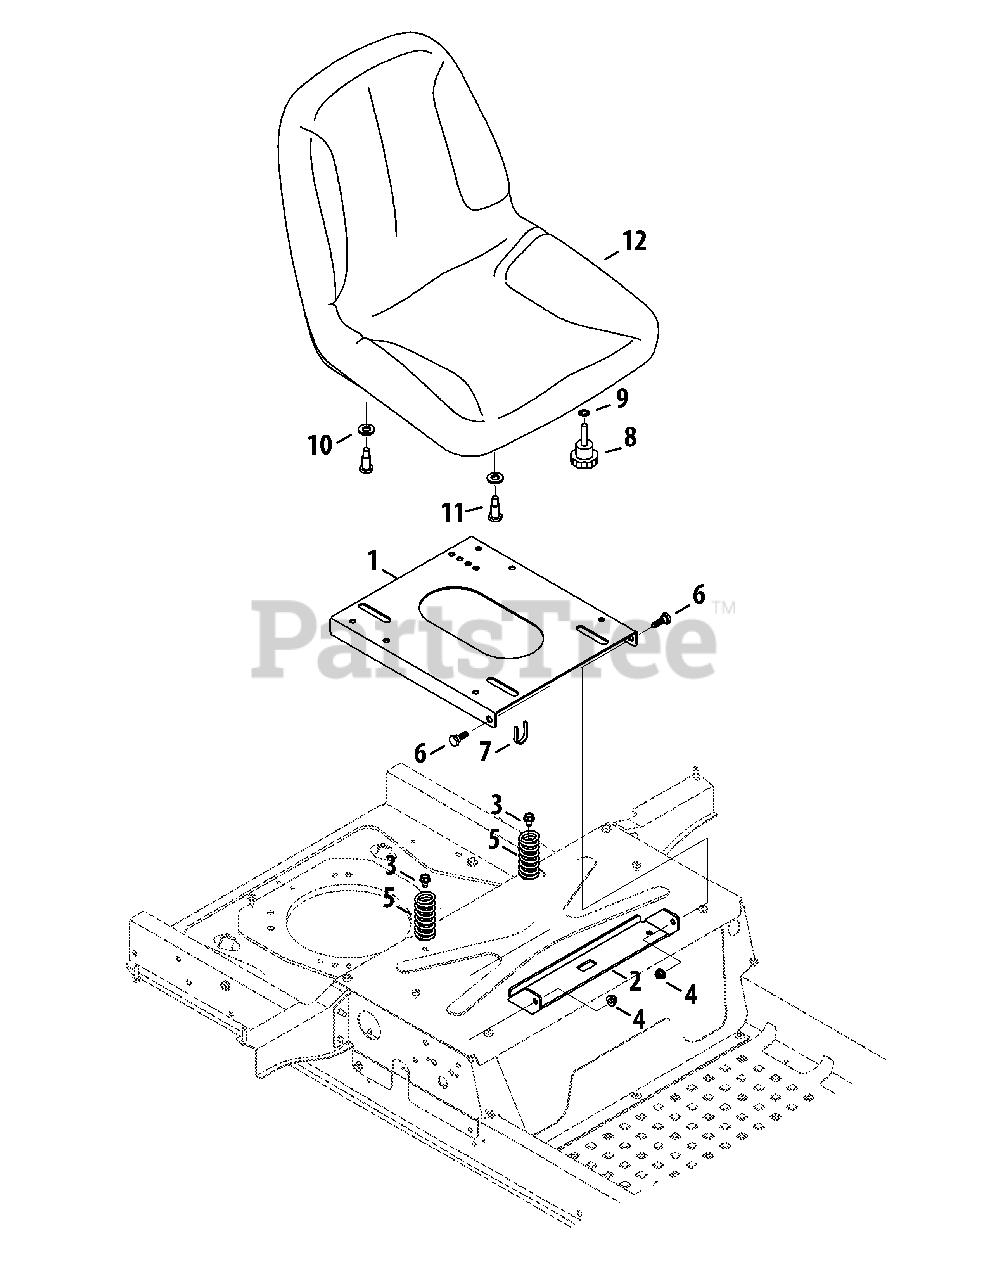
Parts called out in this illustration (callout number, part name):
1	Seat Mount Bracket
3	Hex Washer Screw, 5/16-18 x .750
4	Flange Lock Nut, 5/16-18
5	Spring, Compression, 1.28 OD x 3.125 Lg
6	Shoulder Screw, .437 x .268, 5/16-18
8	Knob Assembly
9	External Tooth Lock Washer, 3/8
10	Flat Washer, .510 x 1.00 x .125
11	Shoulder Screw, 3/8-16
12	Seat
